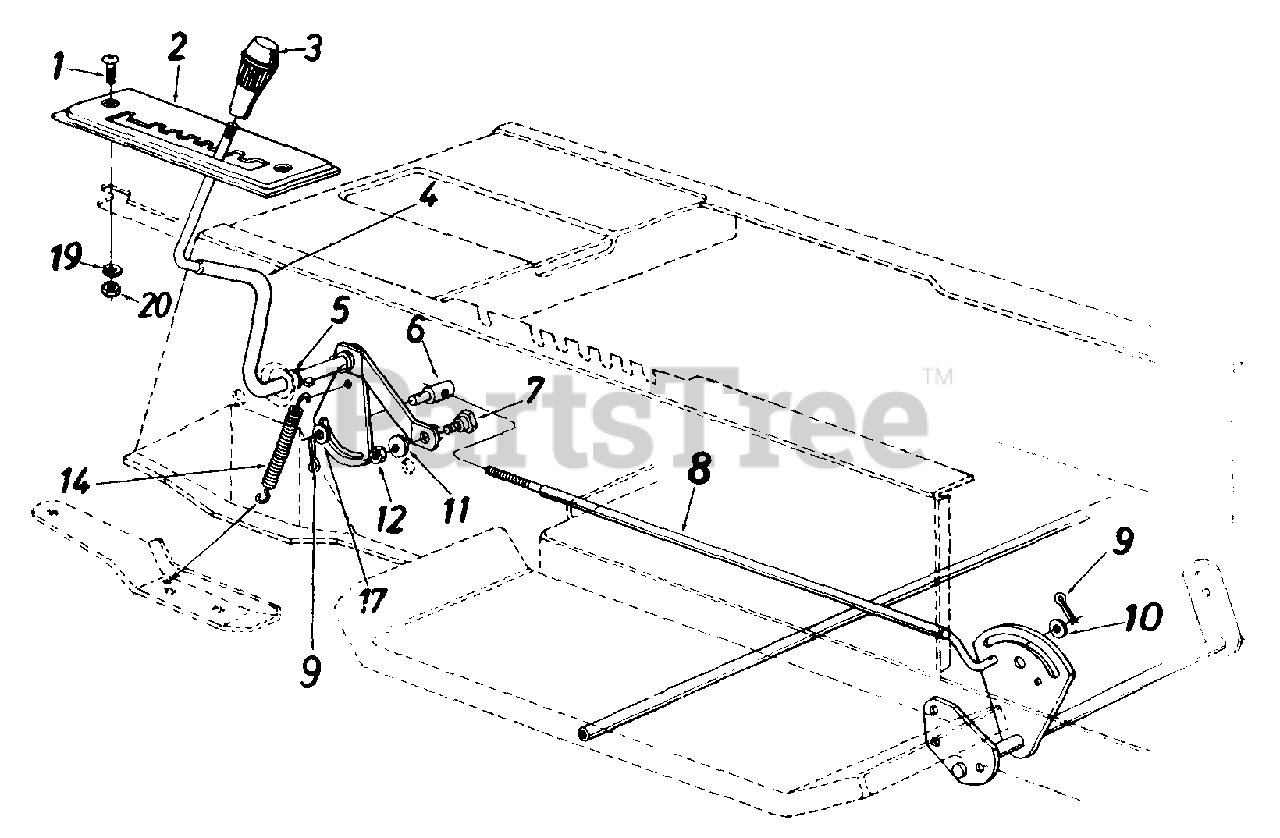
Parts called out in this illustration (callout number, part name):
1	Truss Mach. Scr. 1/4-20 x .75" Lg.
4	Speed Selector Lever Ass'y.
5	Flat Washer .53" I.D. x .93"
6	Ferrule 3/8-24 x .37" Dia.
7	Shoulder Bolt
8	Speed Control Link
9	Cotter Pin 3/32" Dia. x 1.0"
10	Fl-Wash. .469" I.D. x .88"
11	L-Wash. 5/16" I.D.
12	Hex Nut 5/16-18 Thd.
14	Spring .38" O.D. x 3.18" Lg.
17	Fl-Wash. .385" I.D. x .62"
19	L-Wash. 1/4" I.D.
20	Hex Nut 1/4-20 Thd.
